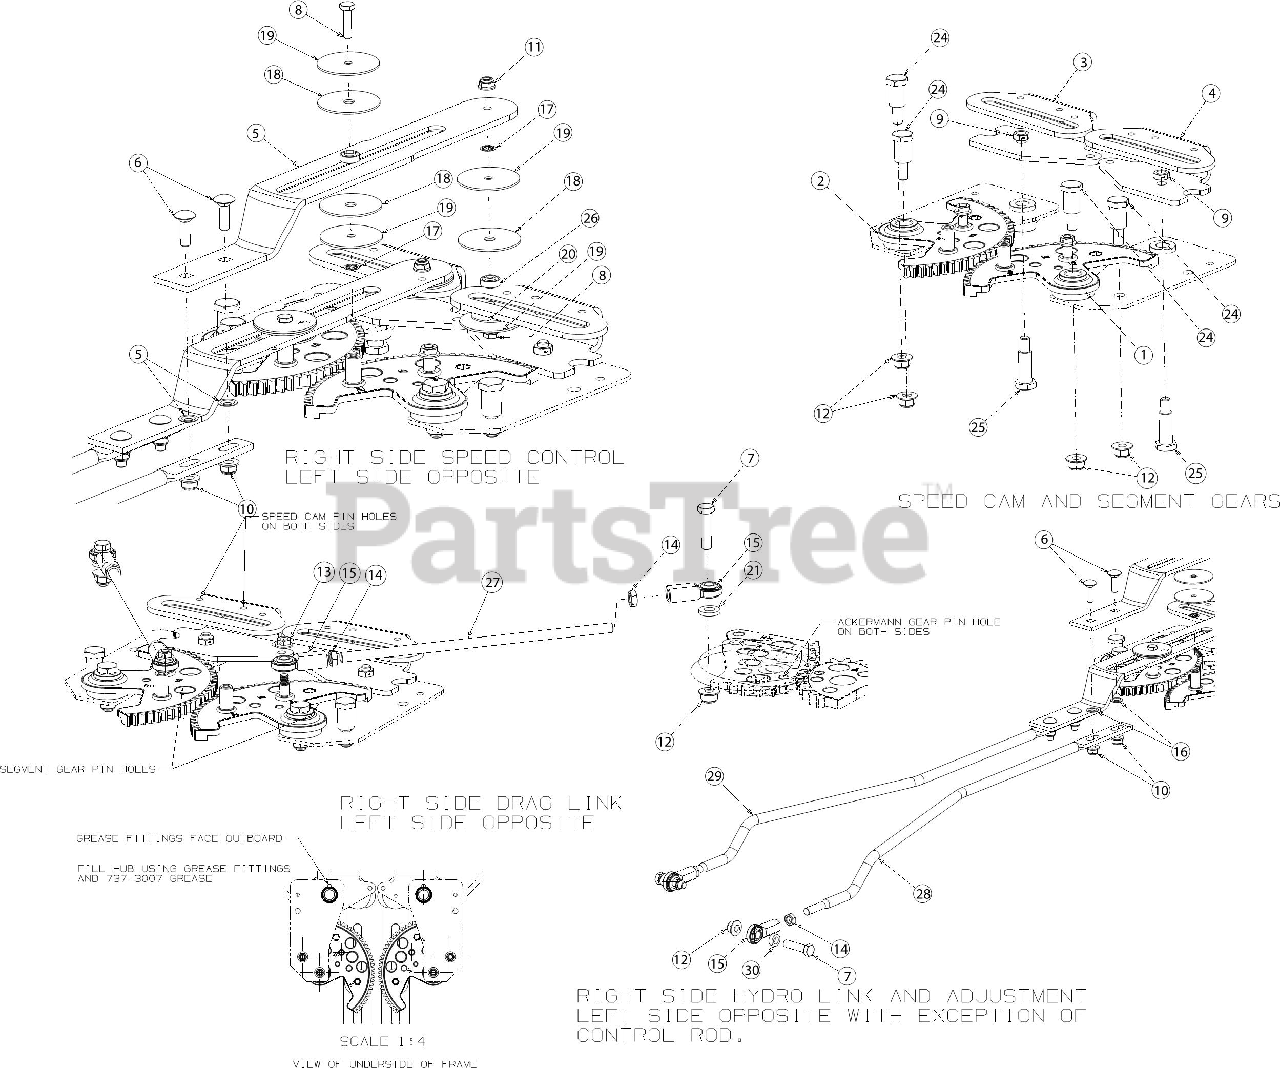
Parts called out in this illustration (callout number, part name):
1	STEERING GEAR ASSEMBLY (RH)
2	STEERING GEAR ASSEMBLY (LH)
3	SPEED CAM PLATE (LH)
4	SPEED CAM PLATE (RH)
5	CONTROL LINK
6	CARRIAGE BOLT 5/16-18 X 1.00
7	SCREW 3/8-16 X 1.50
8	SCREW 1/4-20X1.0 GR5
9	JAM LOCK NUT
10	FLANGE LOCK NUT 5/16-18
11	FLANGE LOCK NUT
13	FLANGE NUT
14	HEX JAM NUT 3/8X24
15	BALL JOINT-(RH)
17	RETAINER-BOLT .25ID x .50OD
18	FLAT WASHER
19	FLAT WASHER
21	FLAT WASHER
22	GREASE FITTING
24	SHOULDER SCREW .625 X .875 X 3/18
25	SHOULDER SCREW .50
26	BALL BEARING .25 X .625 SPCL
27	STEERING DRAG LINK
28	HYDRO LINK ROD (RH)
29	HYDRO LINK ROD (LH)
30	SPACER-.380 ID X.625 OD X .227
